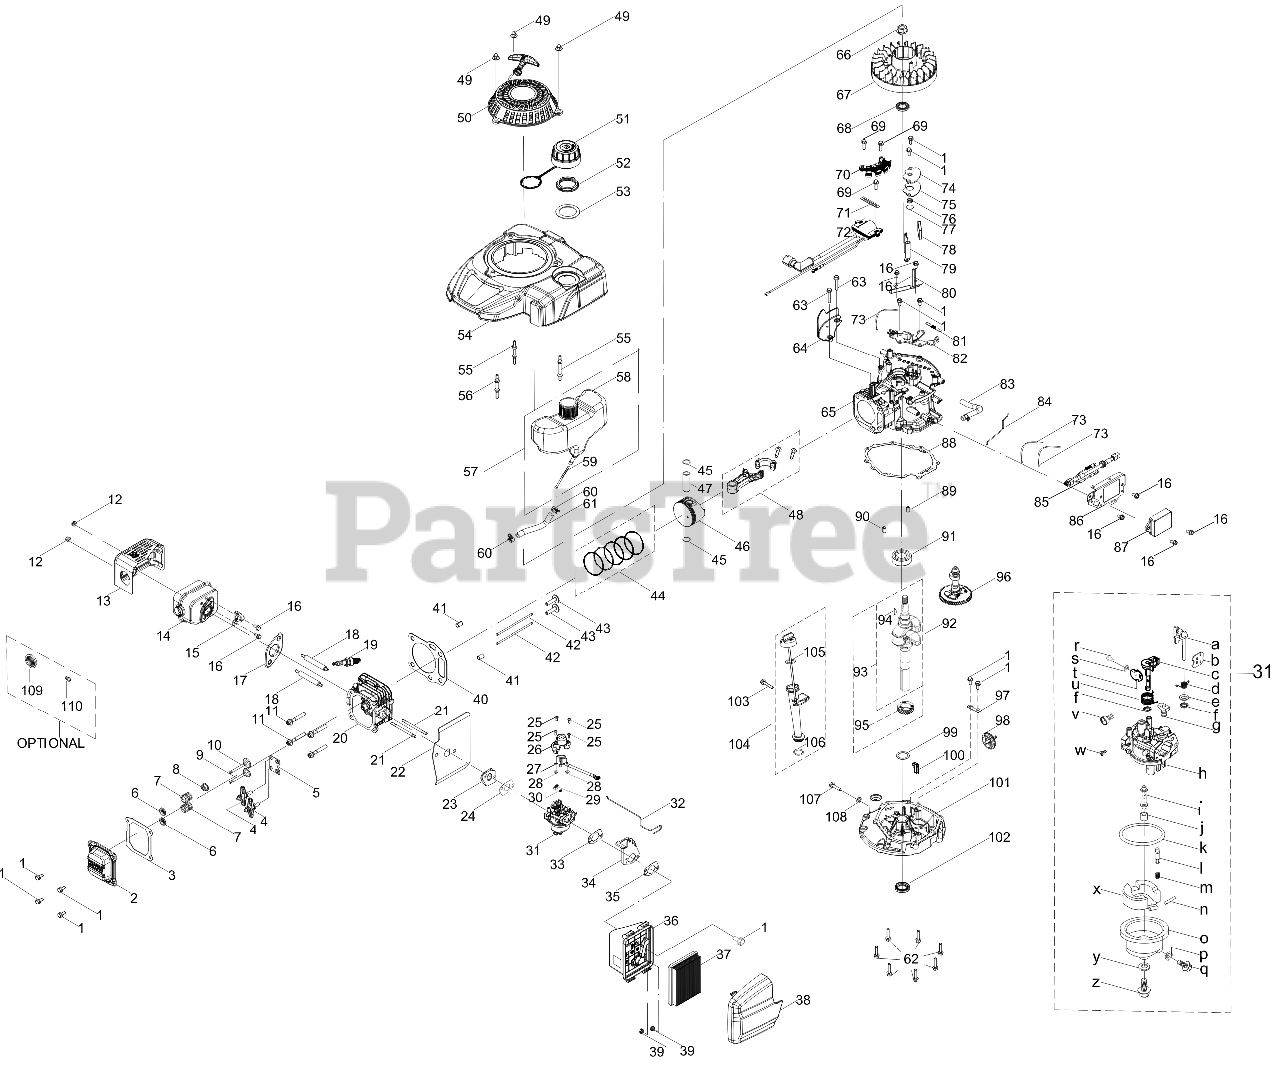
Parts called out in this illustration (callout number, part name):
1	BOLT M6-1 x 14 GR8.8
2	VALVE COVER
3	VALVE COVER GASKET
4	ROCKER ARM ASSEMBLY
5	PUSH ROD GUIDE
6	VALVE SPRING RETAINER
7	VALVE SPRING
8	INTAKE VALVE SEAL
9	EXHAUST VALVE
10	INTAKE VALVE
11	BOLT-M8 x 54
13	MUFFLER SHIELD
14	MUFFLER ASSEMBLY
15	THERMOSTAT
16	BOLT M6-1 x 12 GR8.8
17	MUFFLER GASKET
18	STUD M6-1 x 95
19	SPARK PLUG
20	CYLINDER HEAD
21	CARBURETOR STUD-M6 x 87
22	CARBURETOR GASKET
23	CARBURETOR INSULATOR
24	CARBURETOR GASKET
25	Screw M4×10
26	CARBURETOR MOTOR COVER
27	CARBURETOR MOTOR
29	CARBURETOR MOTOR DAMPER
30	CARBURETOR MOTOR SPRING
31	CARBURETOR
32	CHOKE TEMP CONTROL LINKAGE
33	AIR FILTER BRACKET GASKET
34	AIR FILTER BRACKET
35	AIR FILTER BASE GASKET
36	AIR FILTER BASE
37	AIR FILTER
38	AIR FILTER COVER
40	CYLINDER HEAD GASKET
42	PUSH ROD
43	TAPPET
44	PISTON RING SET
45	SNAP RING-PISTON PIN
46	PISTON
47	PISTON PIN
48	CONNECTING ROD ASSEMBLY
49	ACORN NUT
50	RECOIL STARTER ASSEMBLY
51	FUEL CAP W/TETHER
52	FUEL TANK NUT
53	FUEL TANK UPPER GROMMET
54	ENGINE SHROUD W/O IGNITION SWITCH
55	STARTER/SHROUD REAR STUD
56	STARTER/SHROUD FRONT STUD
57	FUEL TANK ASSEMBLY
58	FUEL TANK
59	FUEL FILTER
60	HOSE CLAMP
61	FUEL HOSE
62	BOLT-M6-1 x 28 GR8.8
63	BOLT M6-1 x 25 GR8.8
64	ENGINE BRAKE COVER PLATE
65	CRANKCASE
66	FLYWHEEL NUT
67	FLYWHEEL
68	CRANKSHAFT SEAL
69	BOLT M6-1 x 20 GR8.8
70	ALTERNATOR
71	FLEXIBLE CLAMP
72	IGNITION COIL ASSEMBLY
73	CABLE TIE - 3 x 150
74	BREATHER COVER PLATE
75	BREATHER GASKET
76	BREATHER VALVE SPRING
77	BREATHER VALVE
78	BREATHER SCREEN
79	AIR VANE
80	AIR VANE BRACKET
81	ENGINE BRAKE SPRING
82	BRAKE ASSEMBLY
83	BREATHER HOSE ASSEMBLY
84	CHOKE LINKAGE
85	WIRE HARNESS
86	CONTROL MODULE BRACKET
87	CONTORL MODULE EGOV
88	CRANKCASE COVER GASKET
89	DOWEL PIN
90	DOWEL PIN
92	CRANKSHAFT ASSEMBLY
93	CRANKSHAFT
94	FLYWHEEL KEY
95	CRANKSHAFT TIMING GEAR
96	CAMSHAFT ASSEMBLY
97	GOVERNOR GEAR MOUNTING PLATE
98	GOVERNOR GEAR
99	THRUST WASHER
100	OIL RETURN SEAL
101	CRANKCASE COVER
102	LOWER CRANKSHAFT SEAL
103	BOLT M6-1 x 35 GR8.8
104	OIL DIPSTICK ASSEMBLY
105	O-RING
107	OIL DRAIN PLUG
108	WASHER
109	SPARK ARRESTOR
110	SCREW M3.5 x 9.5
S	Throttle Plate Lock Washer
